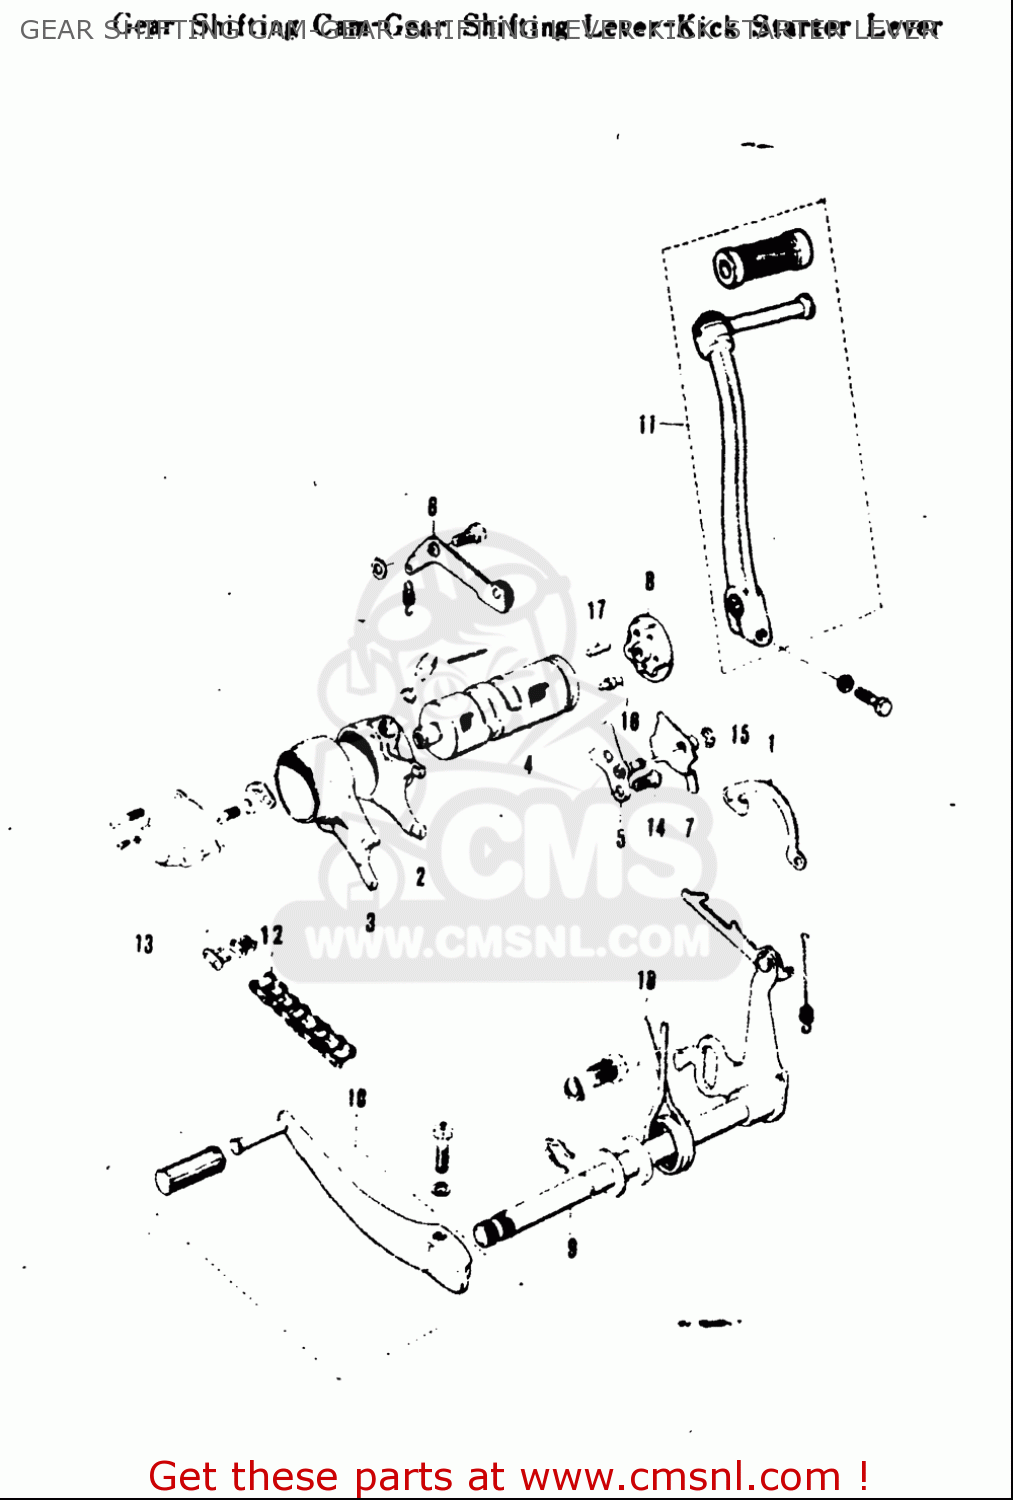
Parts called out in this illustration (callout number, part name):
3	FORK,GEAR SHIFT NO.2
5	GUIDE,GEAR SHIFT CAM
7	PAWL,GEAR SHIFT CAM STOPPER
9	SHAFT,GEAR SHIFT
14	SCREW
15	E RING
17	PIN(4X20)
18	SPRING
